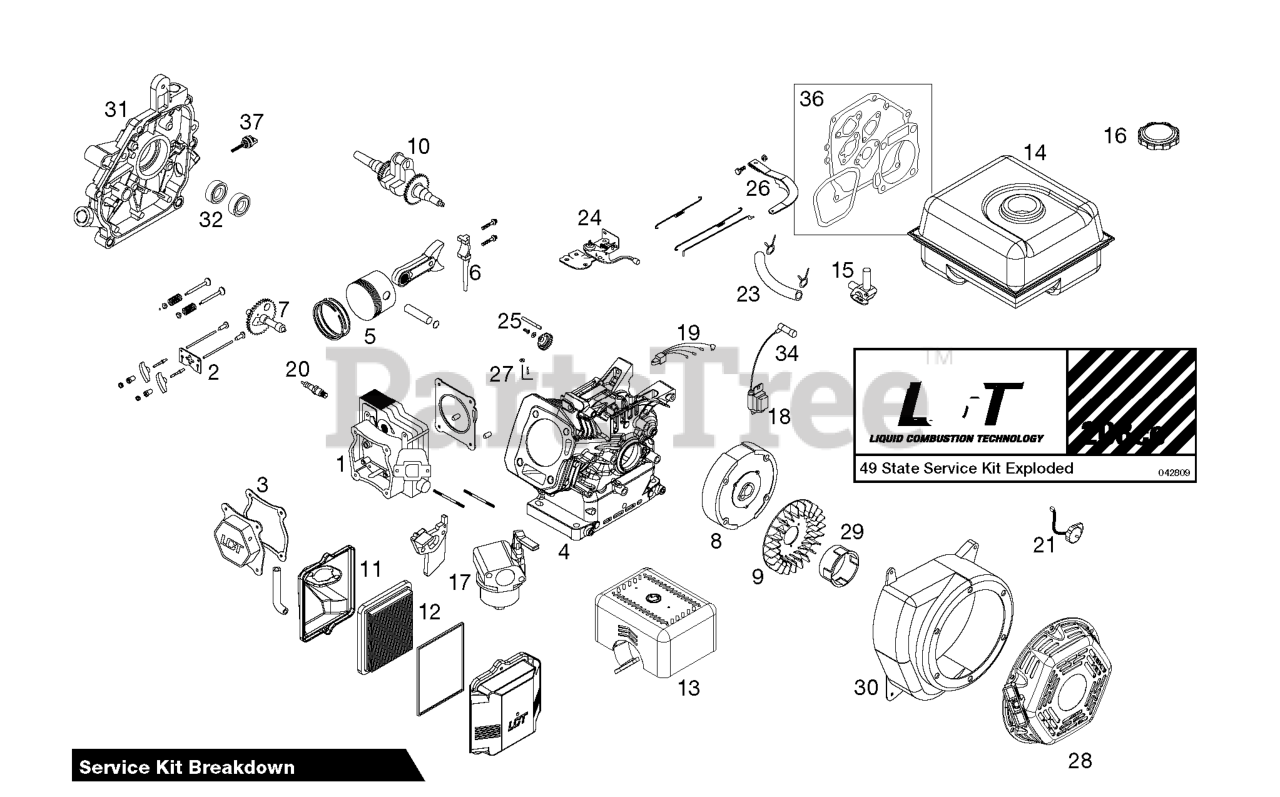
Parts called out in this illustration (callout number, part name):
1	CYLINDR.HEAD.SRV.KIT W/GASKET
2	KIT.PUSH.ROD.SRV(SK208-1001)
3	VALVE COVER ASSEMBLY
4	KIT.CYLINDER.SRV(SK208-1300)
5	KIT.PISTON.SRV(SK208-1400)
6	KIT.CONNECT.ROD.SRV(SK208-1500
7	KIT.CAMSHAFT.208CC.LCT
8	RP KIT.FLYWHEEL.SERVICE
9	FLYWHEEL FAN 420586
10	RP KIT.CRANKSHAFT.SRV
11	KIT.AIRFLTR.ASY.SRV(SK208-2002
12	KIT.SERV.PAP.FILTER(SK208-2012
13	KIT.49STATE.MUFFLER(SK208-2101
14	KIT.49STATE.FUEL.TK(SK208-2200
15	FUEL.PETCOCK.LQA.3/16".LCT
16	KIT.49STATE.FUEL.TK(SK208-2300
17	KIT.CARBURETOR.SERV(SK20-2401)
18	KIT.IGNITION.COIL
19	KIT.IGNITION.(CDI BOX)
20	KIT.SPARK.PLUG.SRV(SK1500)
21	KIT.ENGINE.ON/OFF.LCT.208CC
23	KIT.FUEL.HOSE(SK208-6000)
24	KIT.THROTTLE.CONTRL(SK206-2800
25	KIT.GOVERNOR.GEAR(SK208-2900)
26	RP_IT.GOVERNOR.ARM(SUMMER ENG)
27	KIT.GOVERNOR.CRANK(SK208-3100)
28	KIT.RECOIL.STARTER(HEX) BLACK
29	KIT.STARTER.CUP.SRV(SK208-3300
30	KIT.BLOWER.HSG.SRV(SK208-3400)
31	CRANKCASE COVER ASSY
32	KIT.SEAL.SERVICE(SK208-3900)
34	RP KIT.SPARK.PLUG.BOOT
36	GASKET.KIT.208CC(SK2084300.1)
37	DIPSTICK SMALL
